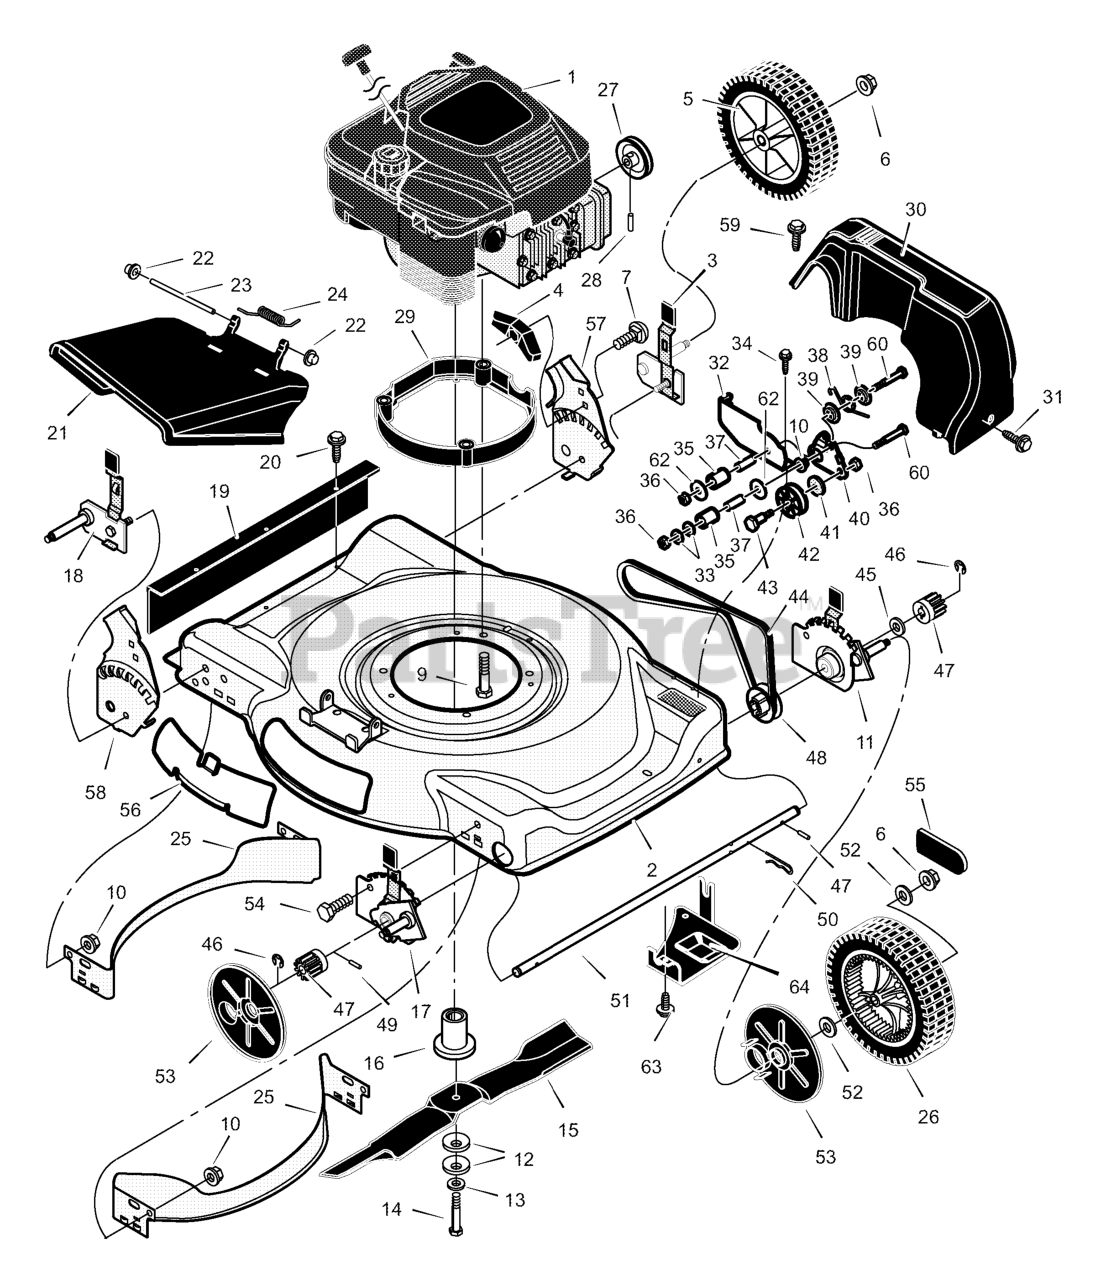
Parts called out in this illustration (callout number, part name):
1	Engine
2	Housing
3	Height Adjuster, Left Rear
5	Wheel and Tire, Rear
6	Locknut, Flange
7	Bolt, Carriage
9	Bolt, Engine
10	Nut
11	Height Adjuster, Left Front
12	Washer, Belleville
14	Bolt, Hex
15	Blade, Mulcher
16	Adapter, Blade
17	Height, Adjuster, Right Frt.
18	Height, Adjuster, Right Rr.
19	Guard, Rear
21	Deflector, Chute
22	Push-On Cap
23	Pin, Pivot
26	Wheel and Tire, Drive
28	Pin, Spring
29	Base, Engine
30	Cover, Belt (Black)
32	Bracket, Idler Support
33	Washer
35	Idler, Backside
36	Locknut
37	Bearing
40	Arm, Pivot
42	Pulley, Idler
43	Bolt, Shoulder
44	Belt, Briggs & Stratton
46	Ring, Retainer
47	Gear, Pinion
49	Pin, Drive
50	Pin, Hair
52	Washer
53	Cover, Dust
54	Bolt
55	Hub Cap
56	Plate, Mulch
57	Bracket, Left Handle
58	Bracket, Right Handle
64	Shield, Debris
